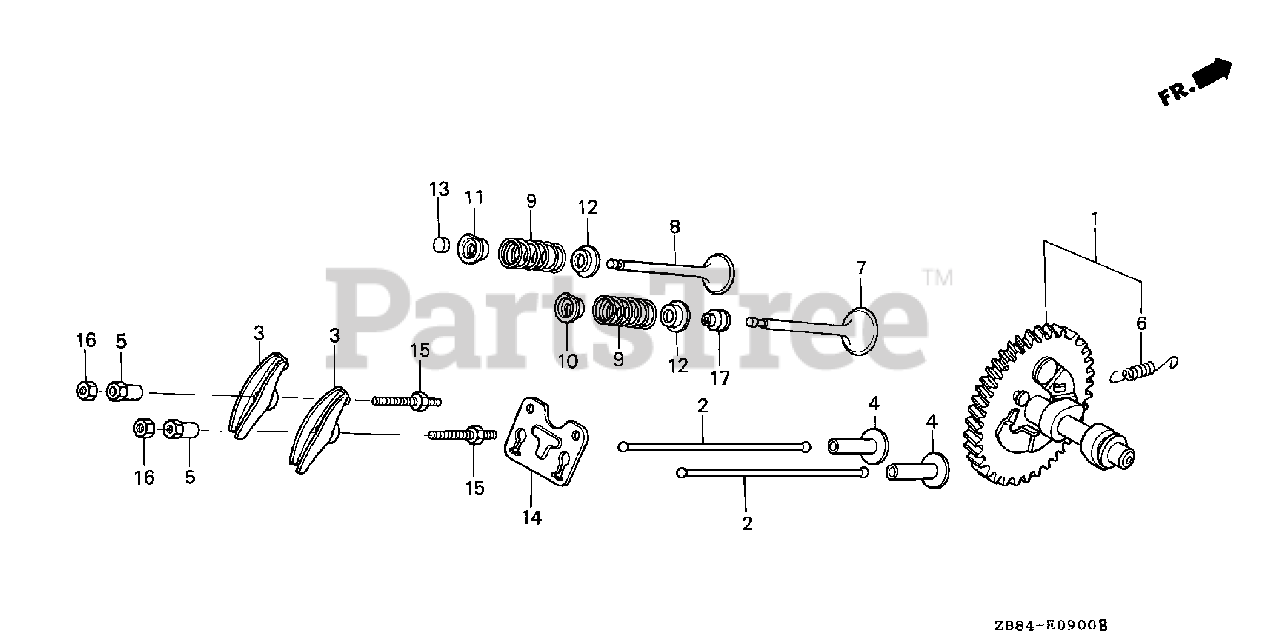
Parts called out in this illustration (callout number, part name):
1	CAMSHAFT ASSY.
2	ROD, PUSH
3	ARM, VALVE ROCKER
4	LIFTER, VALVE
5	PIVOT, ROCKER ARM
6	SPRING, WEIGHT RETURN
7	VALVE, IN.
8	VALVE, EX. (STELITE)
8	VALVE, EX.
9	SPRING, VALVE
10	RETAINER, IN. VALVE SPRING
11	RETAINER, EX. VALVE SPRING
12	SEAT, VALVE SPRING
13	ROTATOR, VALVE
14	PLATE, PUSH ROD GUIDE
15	BOLT, PIVOT (8MM)
16	NUT, PIVOT ADJUSTING
